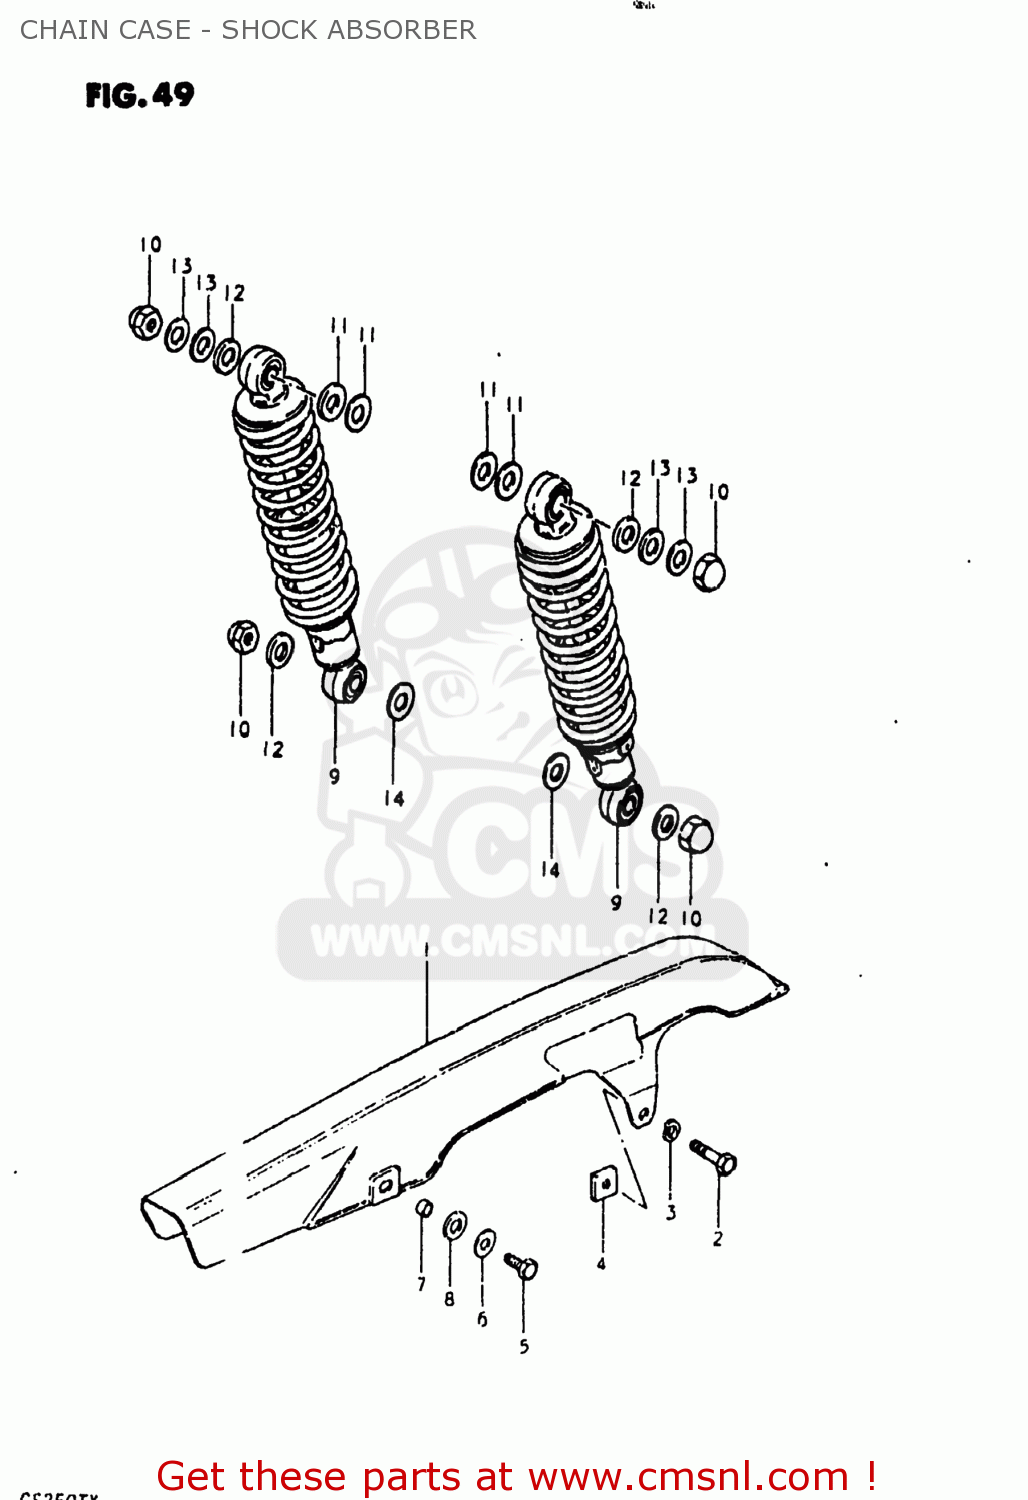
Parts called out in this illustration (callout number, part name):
1	CASE,CHAIN
2	BOLT, UPPER
3	LOCK WASHER
4	NUT,CHAIN CASE RR
5	BOLT
6	WASHER(6.5X18X1)
7	SPACER (6.1X8X5.2)
8	CUSHION
9	ABSORBER ASSEMBLY,REAR SHOCK
10	NUT, LOWER LH
11	WASHER
12	WASHER
13	WASHER(10.5X24X3.2)
14	WASHER (12.5X24X1.6)
